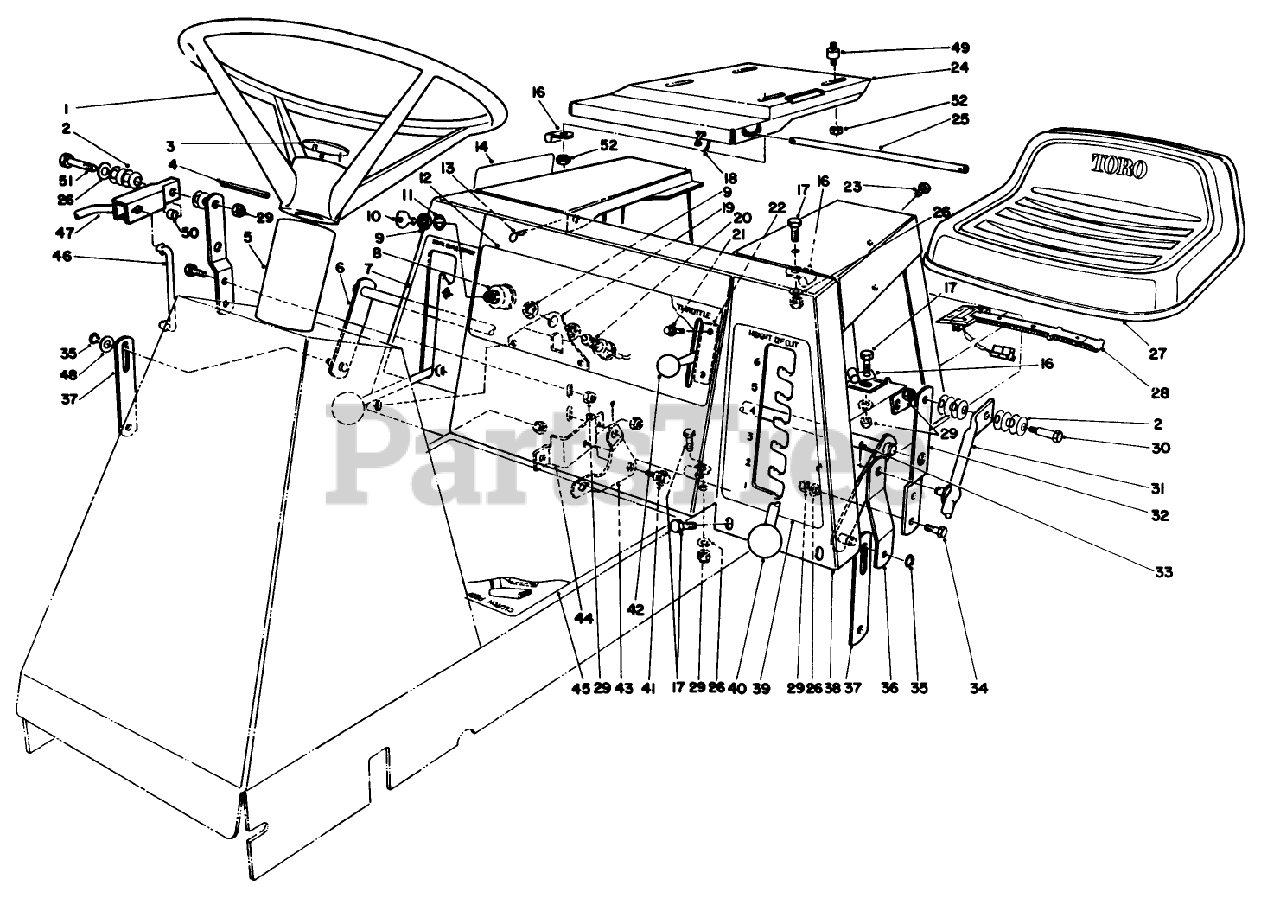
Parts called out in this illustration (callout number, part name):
1	STEERING WHEEL ASM
2	WASHER-BELLEVILLE
4	PIN-ROLL
5	STRG. SHAFT COVER
8	SWITCH-STARTER
9	NUT-HH
11	WASHER-LOCK
16	CLAMP
17	SCREW-HH
18	TIE-CABLE
19	SWITCH MT BRKT
20	DECK SWITCH
21	SCREW-HWHTF
22	THROTTLE CONTROL
23	SCREW-HH
25	SEAT BASE ROD
26	WASHER-PLAIN
28	SWITCH-SEAT
29	NUT-LOCK, NI
30	BOLT-SHOULDER
31	HOC LEVER WA *B
33	PIN-COTTER
34	SCREW-HH
35	RING-RETAINING
39	HOC DECAL
41	SCREW-SHOULDER
43	DECK ENGAGE BELLCRANK
46	BELLCRANK LINK(PLTD)
47	SHIFT LEVER WA *B
48	WASHER-FLAT
49	ISOLATER-SEAT
50	SPACER
51	SCREW-HH
52	NUT-HF
